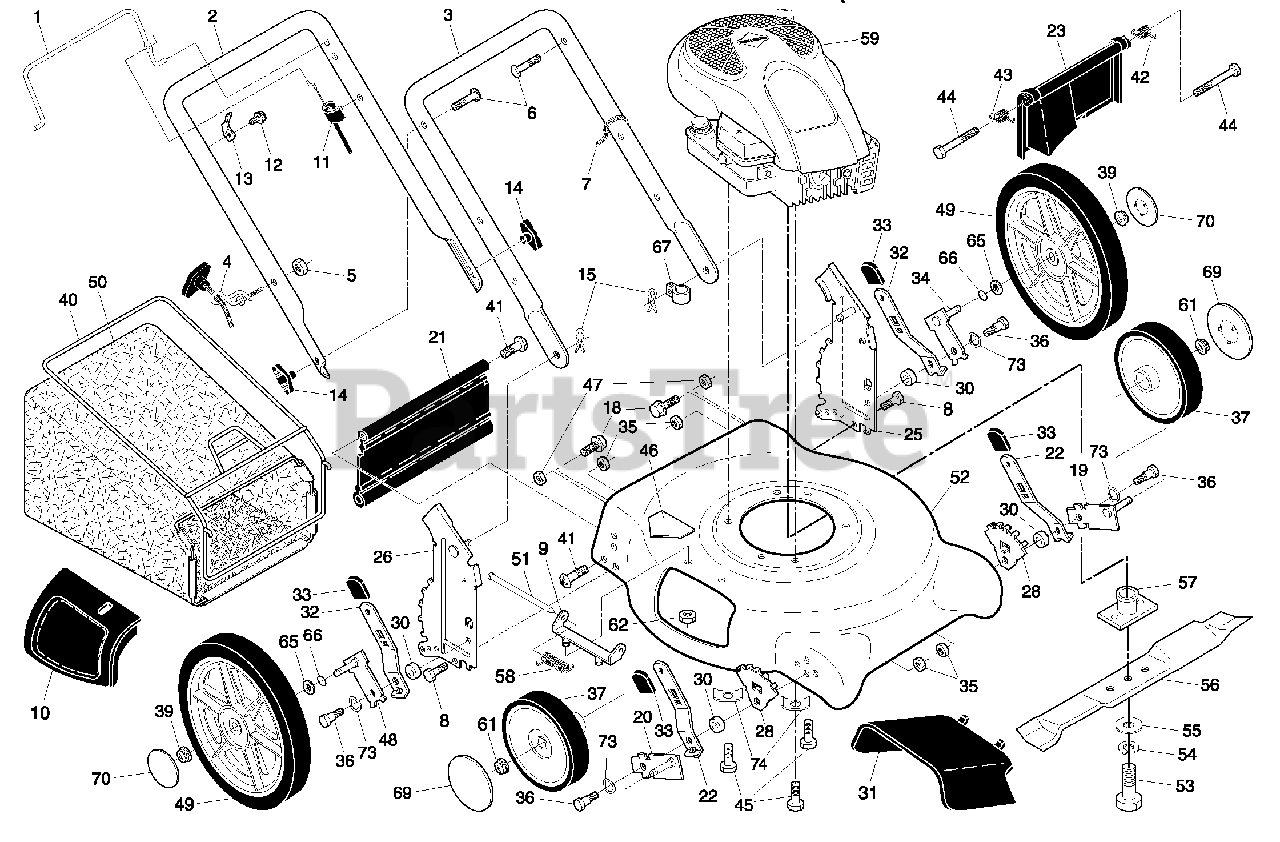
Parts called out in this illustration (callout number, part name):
1	Control Bar
2	Upper Handle
3	Lower Handle
4	Rope Guide
5	Locknut, Hex 1/4-20
6	Handle Bolt
7	Wire Tie
8	Hex Bolt 5/16-18 x 3/4
9	Mounting Bracket, Mulcher Door
10	Mulcher Door
11	Engine Zone Control Cable
12	Hex Washer Head Screw #10-24 x 1/2
13	Up-Stop Bracket
14	Handle Knob
15	Hairpin Cotter
18	Screw
19	Axle Arm Assembly, Front, LH
20	Axle Arm Assembly, Front, RH
21	Rear Skirt
22	Selector Spring, Front
23	Rear Door Assembly
24	Locknut, Hex 5/16-18
25	Handle Bracket, LH
26	Handle Bracket, RH
28	Wheel Adjusting Bracket
30	Spacer
31	Defl ector, Discharge
32	Selector Spring, Rear
33	Selector Knob
34	Axle Arm Assembly, Rear, LH
35	Locknut, Hex 5/16-18
36	Shoulder Bolt 5/16-18
37	Wheel & Tire Assembly, Front, 8"
39	Flanged Locknut
40	Frame, Grassbag
41	Hinge Screw
42	Spring, Rear Door, LH
43	Spring, Rear Door, RH
44	Bolt, Rear Door
45	Screw, Hex Head Thread Rolling Screw 3/8-16 x 1
46	Danger Decal
47	Nut, Hex
48	Axle Arm Assembly, Rear, RH
49	Wheel & Tire Assembly, Rear, 12"
50	Grassbag
51	Rod, Hinge
52	Kit, Lawn Mower Housing
53	Hex Head Screw, Grade 8, 3/8-24 x 1-3/8
54	Helical Lockwasher
55	Hardened Washer
56	21" Blade
57	Blade Adapter
58	Spring, Hinge Rod
61	Flanged Locknut
62	Nut, Hex
65	Washer, Flat 3/8
66	O-Ring
67	Clip, Cable
69	Hubcap, Front Wheel
70	Hubcap, Rear Wheel
73	Washer, Curved, Cylindrical
74	Washer, Special, Engine
74	Operator's Manual, English
74	Operator's Manual, French
74	Repair Parts Manual
